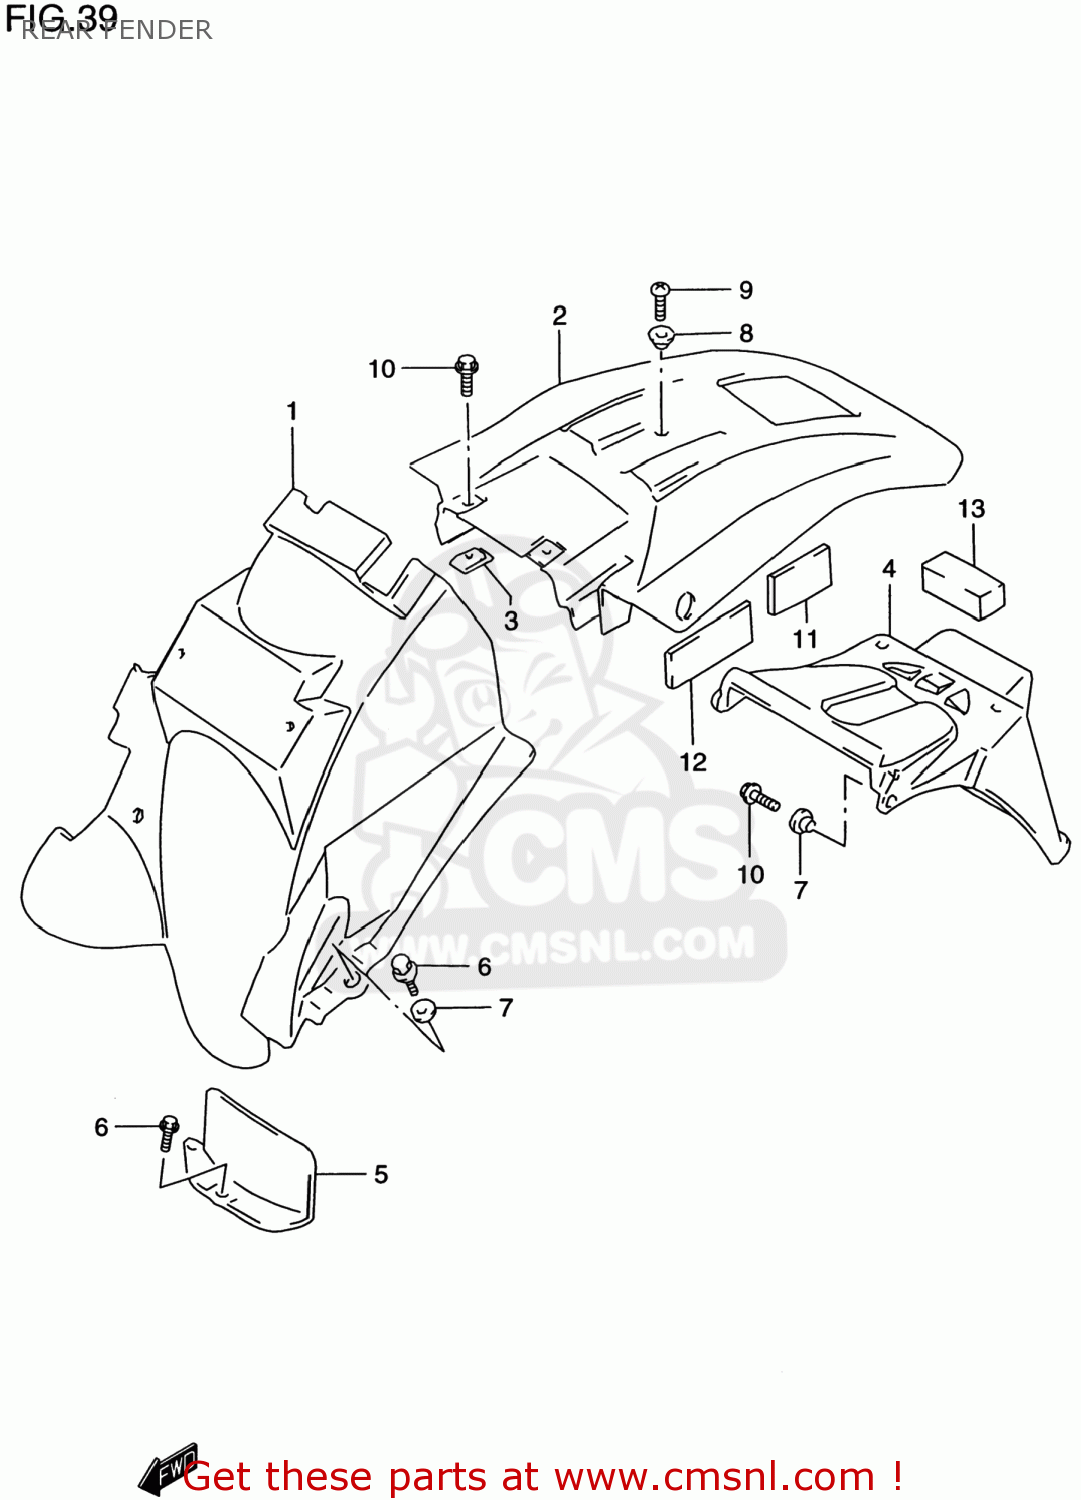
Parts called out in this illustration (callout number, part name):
1	BODY,RR FENDER FR
2	BODY,REAR FENDER,REAR
3	PLATE,FRAME COVER
4	EXTENSION,RR FENDER
5	MUDGUARD,RR FENDER
6	BOLT(6X16)
7	WASHER
8	WASHER
9	SCREW(6X16)
10	BOLT
11	CUSHION
12	CUSHION,RR FENDER
13	CUSHION,EXTENSION
